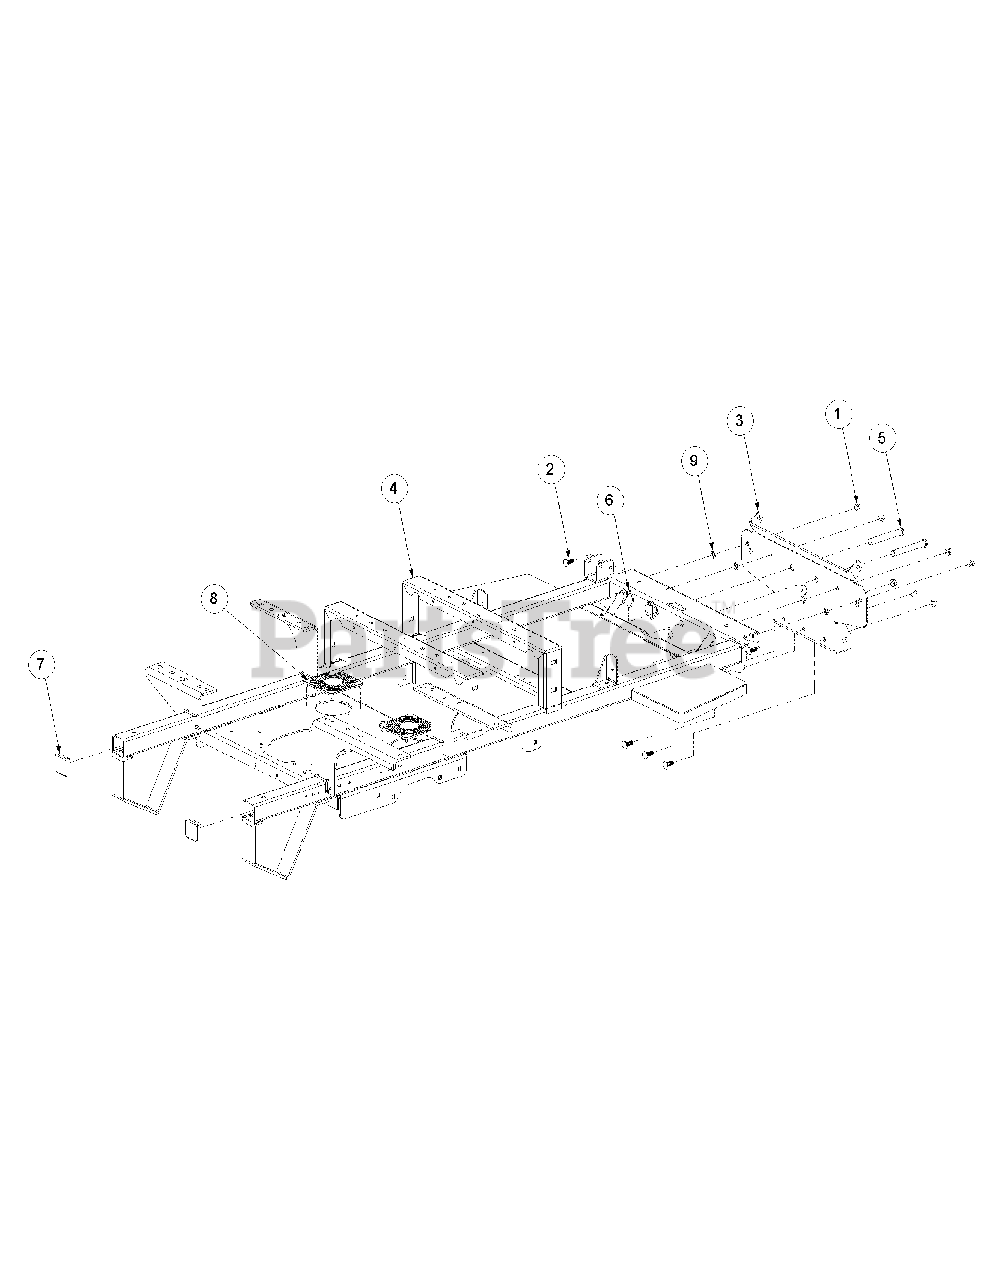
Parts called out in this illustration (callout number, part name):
1	Hex Nut, 3/8-16 Flange Lock
2	Carriage Bolt, 3/8-16 x 1.00 Long
3	Bracket Assembly, Frame, Front
4	Frame Assembly
5	Clevis Pin, .625 Dia x 4.375 Long
6	Linch Pin, 3/16 Dia.
7	Plug, Square Tube
8	Cover, Hydro Fan
9	Push Retainer, 3/8
